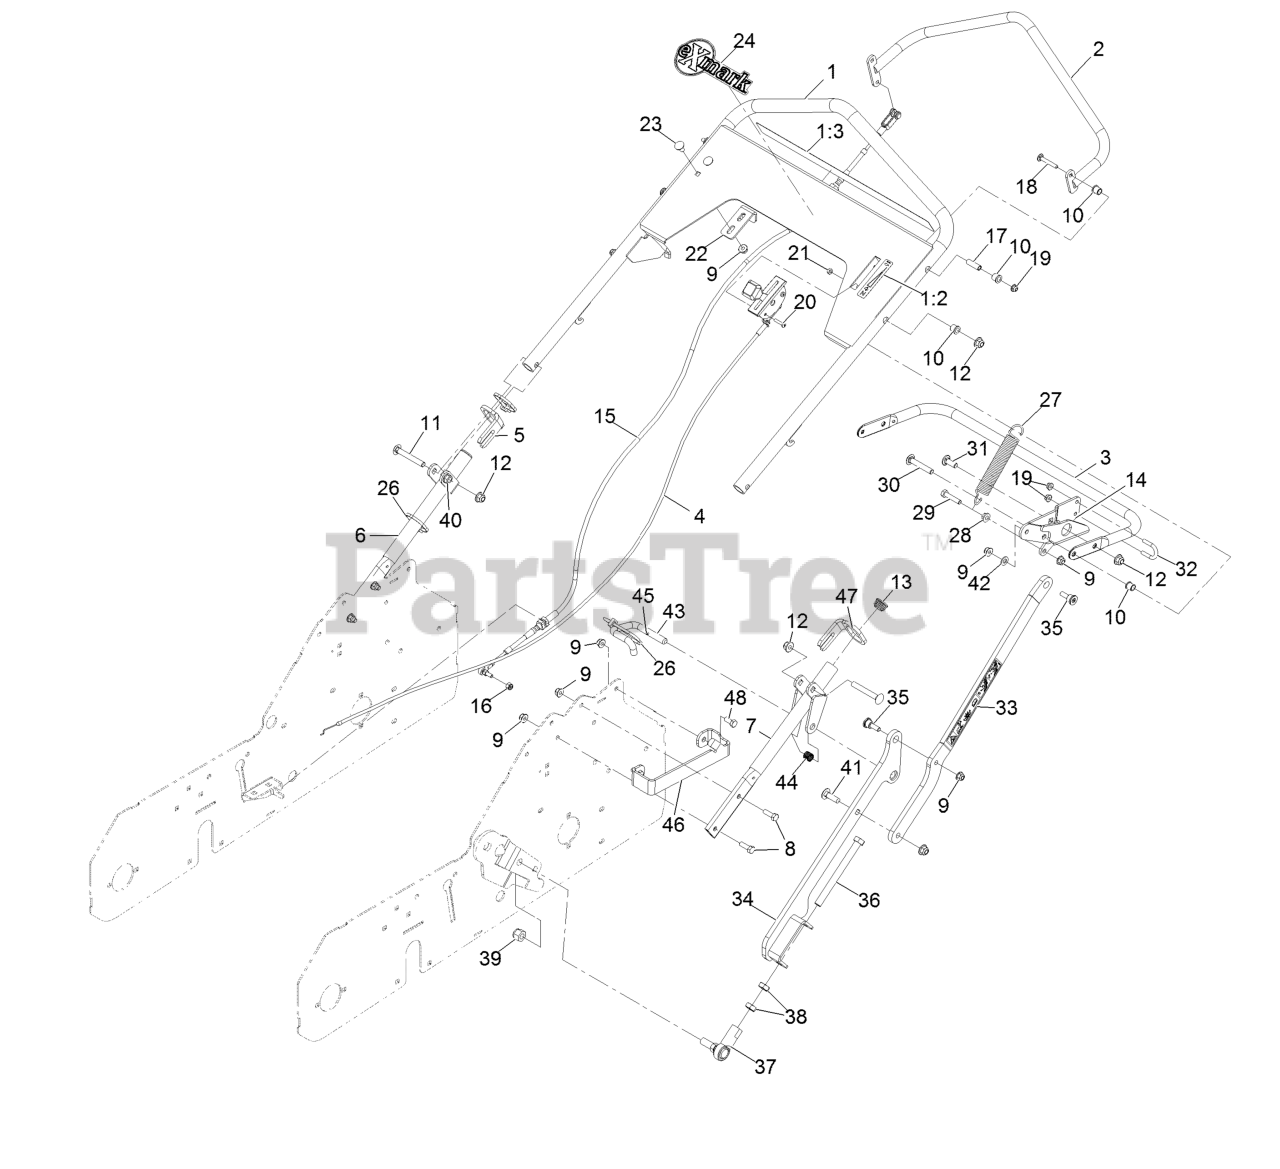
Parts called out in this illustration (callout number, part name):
1	Handle ASM
1:2	Decal-Throttle, Choke
1:3	Decal-Aerator Control Panel
2	Tube-Control
3	Tube-Handle Lift
4	Control-Throttle
5	Ring, Handle Lock
6	Handle-Lower
7	Asm-Lower Handle
8	Screw-HH 5/16-18 X 1
9	Nut-Nyloc 5/16-18 Flg
10	Bearing
11	Screw-CARR
12	Nut-Nyloc 3/8-16 Flg
14	Arm-Upper
16	Nut-Nyloc 1/4-28
17	Bushing-Pivot
18	Screw-CARR
19	Nut-Nyloc 1/4-20 Flg
20	Screw-PPH #10-24 X 7/8
21	Nut-Nyloc #10-24
22	Angle-Stop
23	Bolt-Carriage 5/16-18 X 5/8
24	Decal, Exmark Logo
26	Tie-Cable
27	Spring-Extension
28	Nut-Whizlock 5/16-18
29	Screw-HH 5/16-18 X 1 1/2
30	Bolt-Carriage 3/8-16 X 2 1/4
31	Bolt-Carriage 3/8-16 X 1
33	ASM, Upper Link W/ Decal
34	Arm-Lower
35	Bolt-Shoulder, Groomer
36	Screw-HH 1/2-20 X 5 1/2
37	End-Rod, RH Thread
38	Nut-Jam 1/2-20
39	Nut-Nyloc 1/2-20
40	Nut-Whizlock 3/8-16
41	Bolt-Carriage 3/8-16 X 1 1/4
42	Washer-5/16 SAE
43	Pin-Latch, Tranport
44	Spring-Compression
45	Pin-Spring
46	Strap, Stop
47	Ring, Handle Lock
48	Screw-HH 5/16-18 X 3/4
